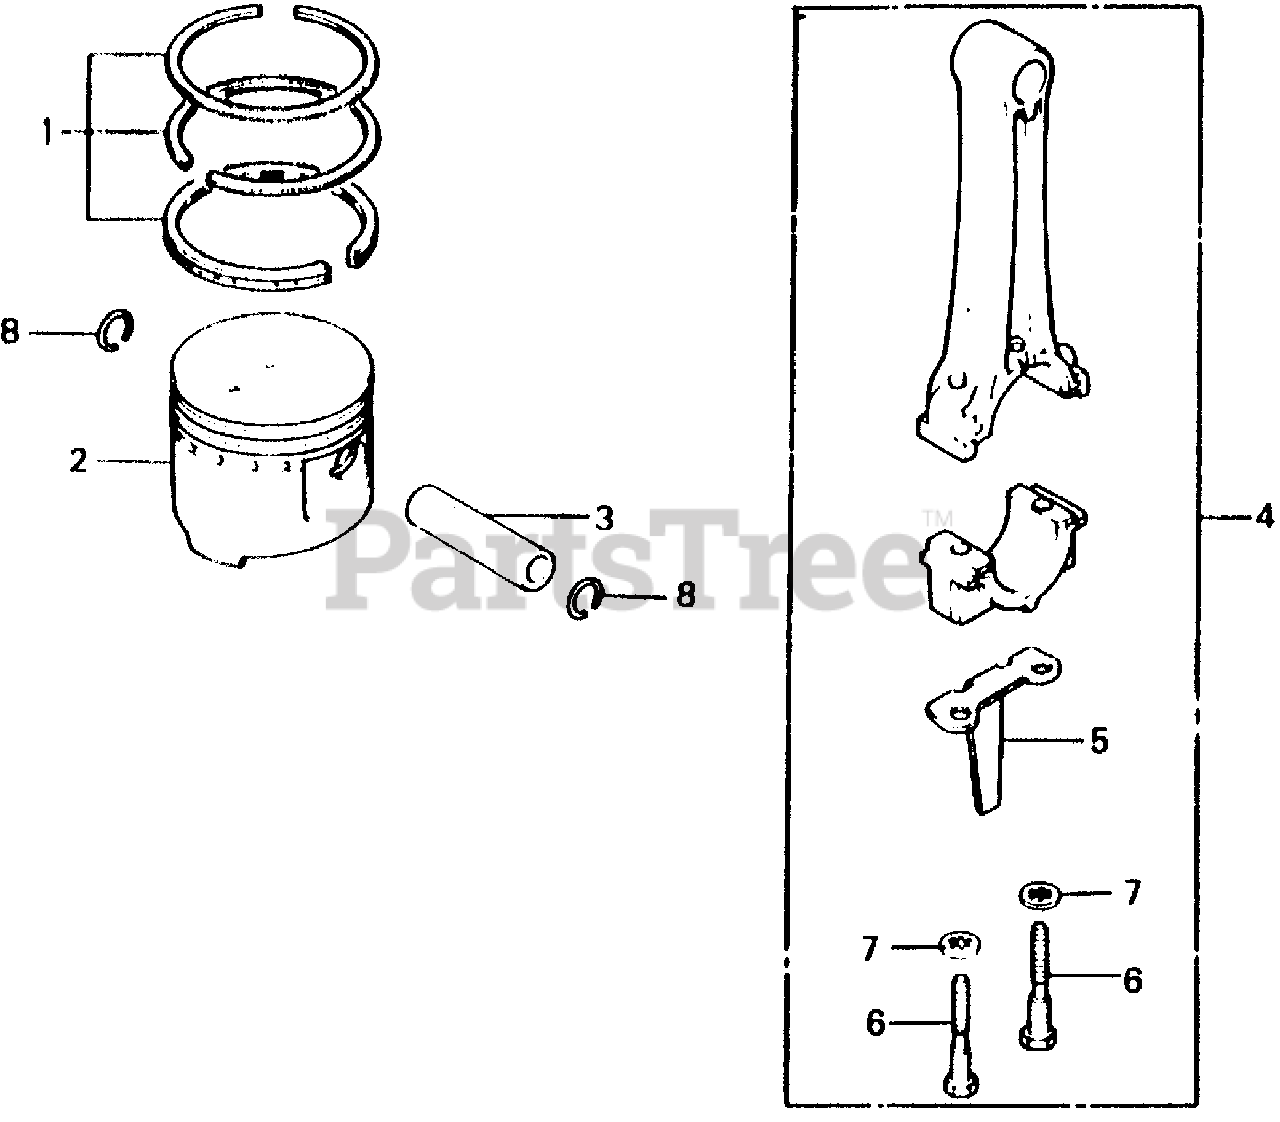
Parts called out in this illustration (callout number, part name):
1	RING SET, PISTON (STD) (NOT AVAILABLE)
1	RING SET, PISTON (OS 0.25)
1	RING SET, PISTON (OS 0.50)
1	RING SET, PISTON (0.75)
2	PISTON (STD)
2	PISTON (OS 0.25) (OS)
2	PISTON (OS 0.50) (OS)
2	PISTON (0.75) (OS)
3	PIN, PISTON
4	ROD ASSY., CONNECTING
5	DIPPER, CONNECTING ROD
6	BOLT, CONNECTING ROD (7MM)
7	WASHER, LOCK (7MM)
8	CLIP, PISTON PIN (15MM)
